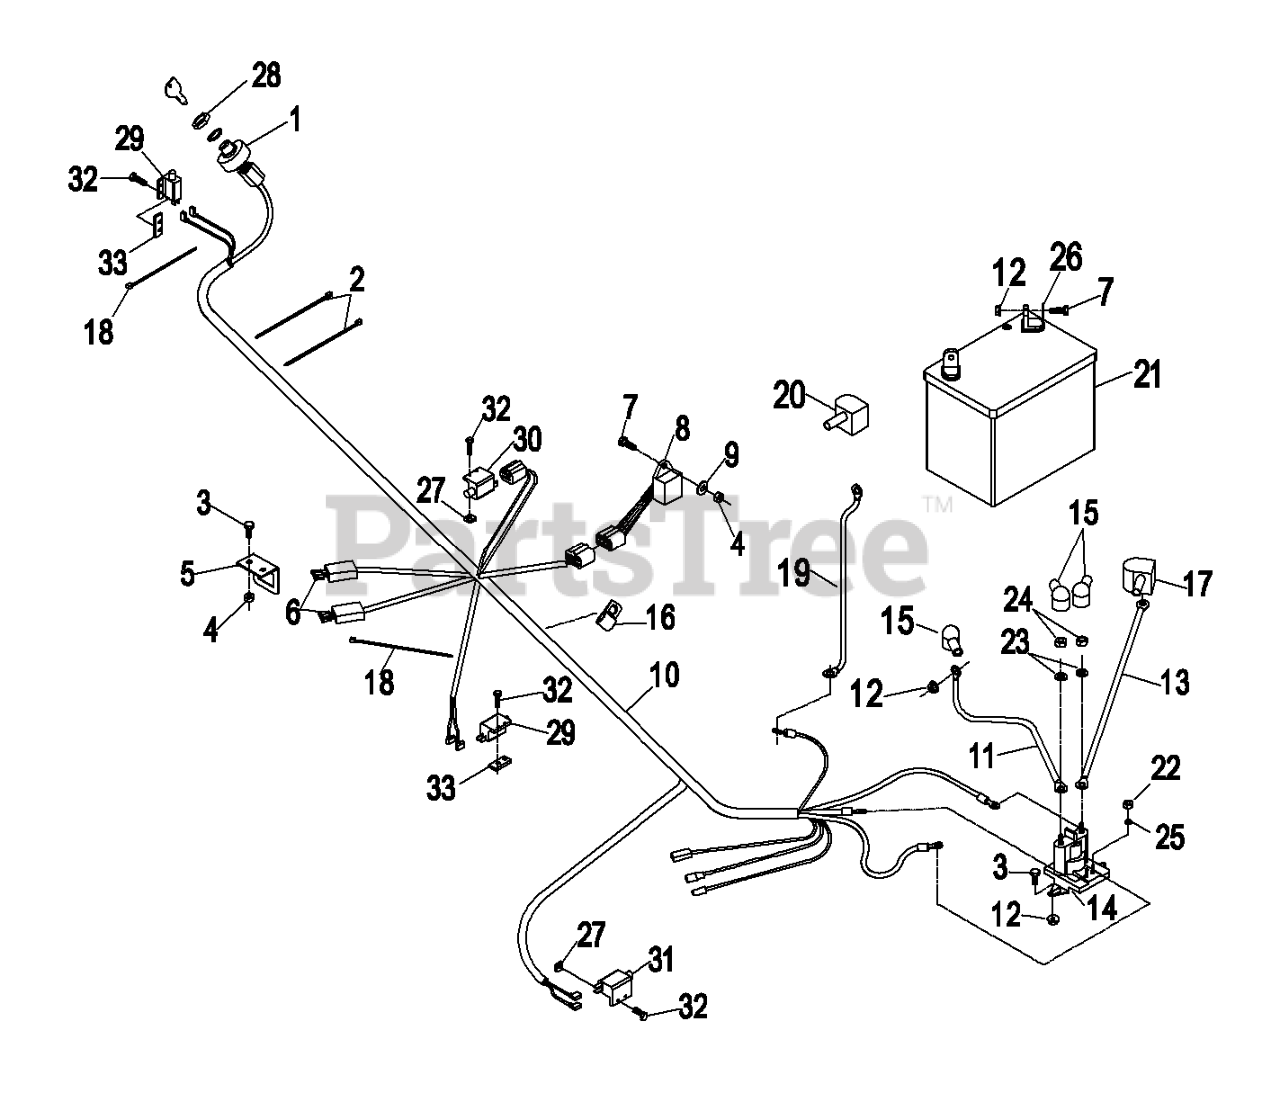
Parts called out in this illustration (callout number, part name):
1	SWITCH,IGNITION
2	TIE-PLASTIC
3	SCREW-HH
4	NUT-LOCK, NI
5	BRACKET,FUSE
6	FUSE-BLADE TYPE, 20 AMP
7	SCREW-HH
8	MODULE-OPC NO TIME DELAY
9	WASHER-FLAT
10	HARNESS,WIRING ELEC ST
15	INSULATOR-SOLENOID
16	CLIP-LOOM
18	TIE-CABLE
19	CABLE-BATTERY, NEGATIVE
20	INSULATOR, BATTERY -
22	NUT-HEX
23	WASHER-LOCK
24	NUT-JAM
25	WASHER-LOCK
26	WASHER-FLAT
27	NUT-SQH
28	NUT-SWITCH, IGNITION
29	SWITCH-OPEN, NORMALLY
31	SWITCH-CLOSED, NORMALLY
32	SCREW-PPH
33	PLATE-TAPPED
